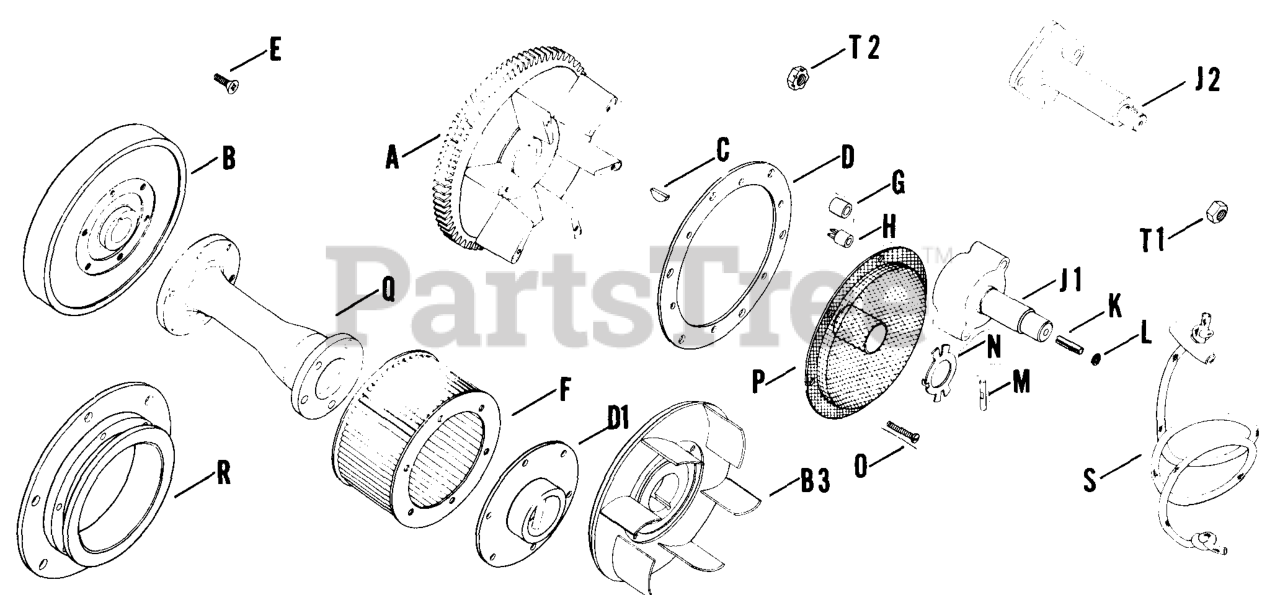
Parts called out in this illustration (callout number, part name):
C	KEY, 1/4" X 1"
G	SPACER - DISCONTINUED
K	Pin, roll
N	NUT - DISCONTINUED
P	SCREEN - USE 270983
S	ROPE-DISCONTINUED
T1	NUT - DISCONTINUED
